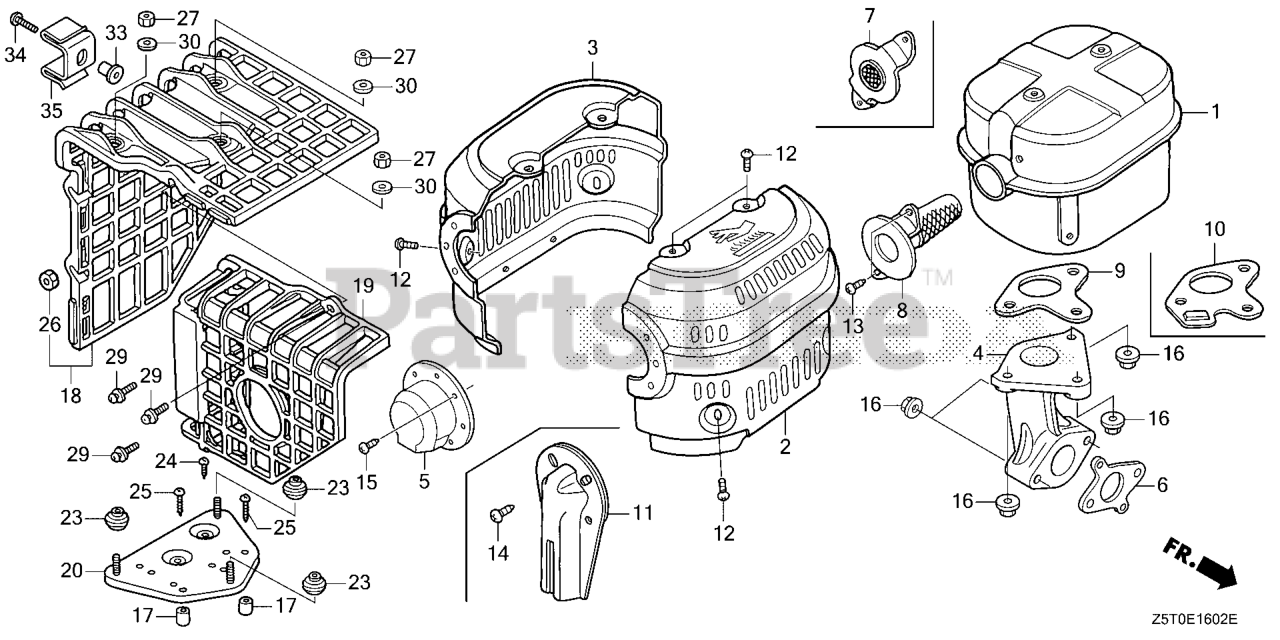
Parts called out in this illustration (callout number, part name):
2	PROTECTOR, R. MUFFLER
3	PROTECTOR, L. MUFFLER
4	PIPE, EX.
6	GASKET, EX. PIPE
7	FLANGE, BAFFLE
8	ARRESTER, SPARK
9	GASKET, MUFFLER (THAI LEAKLESS)
12	SCREW, TAPPING (5X8)
13	SCREW, TAPPING (5X8)
16	NUT, FLANGE (8MM)
17	COLLAR, AIR CLEANER HOUSING
18	COVER, MUFFLER
19	COVER, RR. MUFFLER
20	BASE, MUFFLER COVER
23	SPACER, MUFFLER COVER
24	SCREW, TAPPING (5X8)
25	SCREW, TAPPING (5X25)
26	NUT, U (6MM)
27	NUT, HEX. (5MM)
29	SCREW-WASHER (6X20)
30	WASHER, PLAIN (5MM)
33	COLLAR, FAN COVER (Honda Code 5580527). (N/A: SEE ASSEMBLY)
34	SCREW, TAPPING (6X25)
35	STAY, MUFFLER COVER
